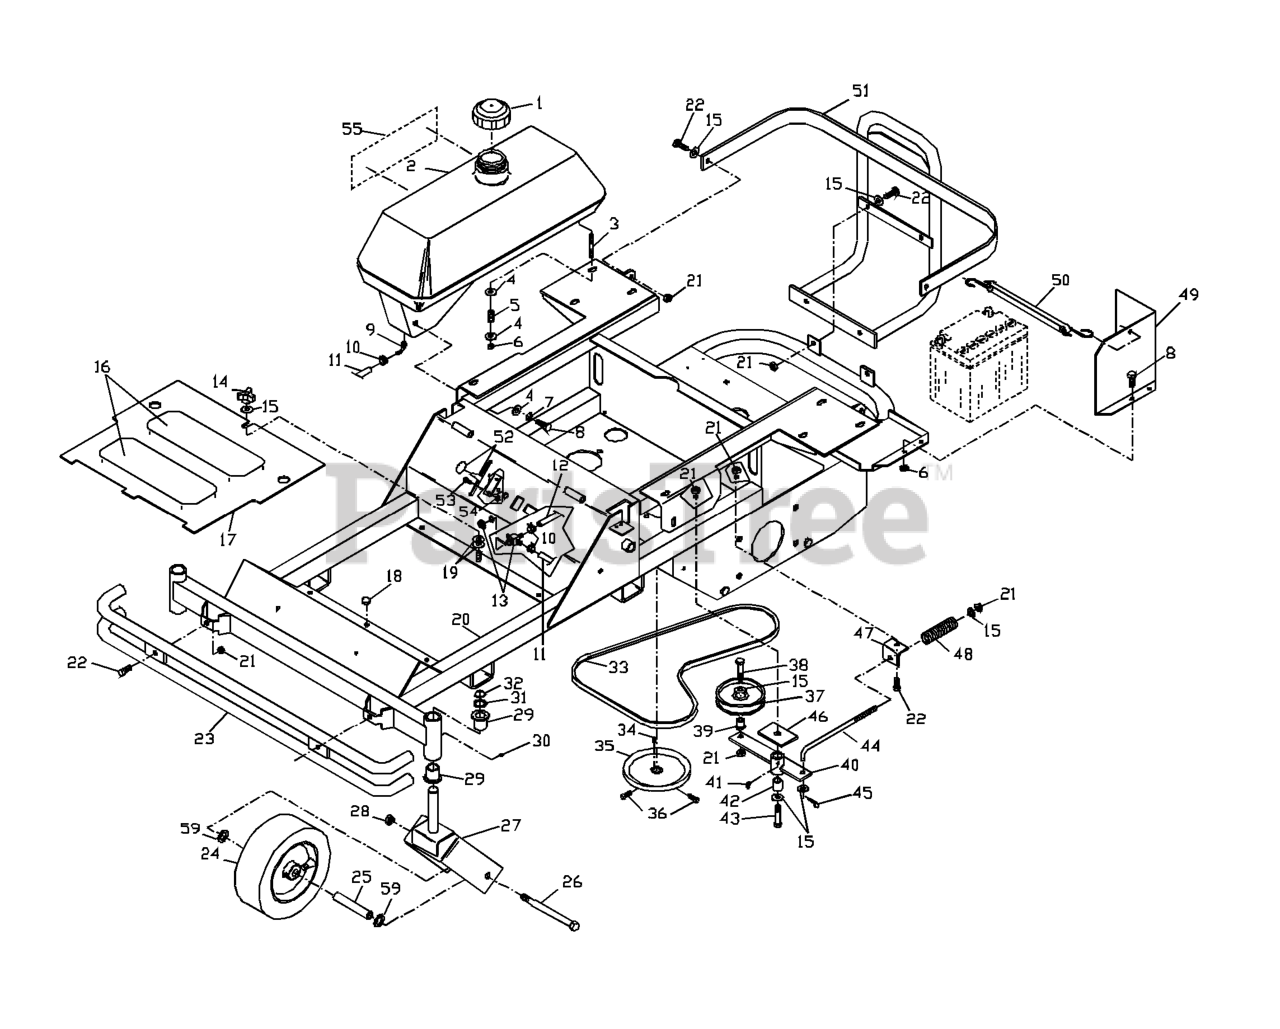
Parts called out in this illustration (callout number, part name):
1	FUEL CAP
2	FUEL TANK RT
3	STUD, 5/16C
4	WASHER 5/16 FLAT
6	NUT 5/16C CENTERLOCK
7	WASHER.LOCK.HVY.HLCL.SPR.5/16
8	HCS 5/16C X 3/4
9	HOSE BARB 90 DEGREE
10	HOSE CLAMP
11	FUEL LINE 21.5" TANK
12	FUEL LINE, ENGINE
13	FUEL VALVE
14	KNOB, THREE PRONG
15	WASHER 3/8 FLAT
16	ANTI-SKID PAD
17	FOOTPLATE
18	GROMMET, BUMPER
19	WASHER, 3/8 DISC SPRING SPEC
20	FRAME W/DECALS KAWASAKI
20	FRAME W/DECALS KOHLER
21	NUT 3/8C CENTERBLOCK
22	HCS 3/8-16X1.GRD.5.ZD
23	BUMPER, FRONT
24	TIRE, CASTER (COMPLETE)
24	TIRE.11X4.00-5NHS.4PR.SMOOTH
24	ROLLER BEARING-CAGED 3 1/4'
24	ZERK
24	BEARING RETAINER
26	HCS 1/2C X 5 1/2
27	YOKE WELDMENT ORANGE
28	NUT 1/2-13 HEX NYLOC ZD
29	BUSHING, FLANGED
30	ZERK
31	BSHG .875 X 1.375 X .074 ZD
32	RETAINING RING, 7/8"
34	KEY 5 MM SQ X 25 MM
36	SCREW 5/16C X 5/8 SQ HEAD
37	IDLER PULLEY
38	HCS 3/8-16 X 1 3/4 GR5
39	BUSHING, IDLER FLANGE
40	IDLER ARM WELDMENT
41	ZERK
42	PIVOT BUSHING
43	HCS 3/8C X 3
44	TENSION ROD
45	RP_COTTER PIN 1/8 X 3/4
46	SUPPORT PLATE
47	TENSION BRACKET
48	COMPRESSION SPRING
49	BATTERY GUARD W/DECA
50	BATTERY STRAP
51	ENGINE GUARD W/DECAL
52	THROTTLE CABLE
53	HCS #10-24 X 1/2
54	NUT 10-24 NYLOC
55	DECAL, ZTH4218
55	DECAL ZTH4221
55	DECAL, ZTH4818
55	DECAL ZTH4820
55	DECAL, ZTH4821
56	HCS 3/8C X 2 1/4
57	WEIGHT BLOCK
58	CHOKE CONTROL, COMPLETE
